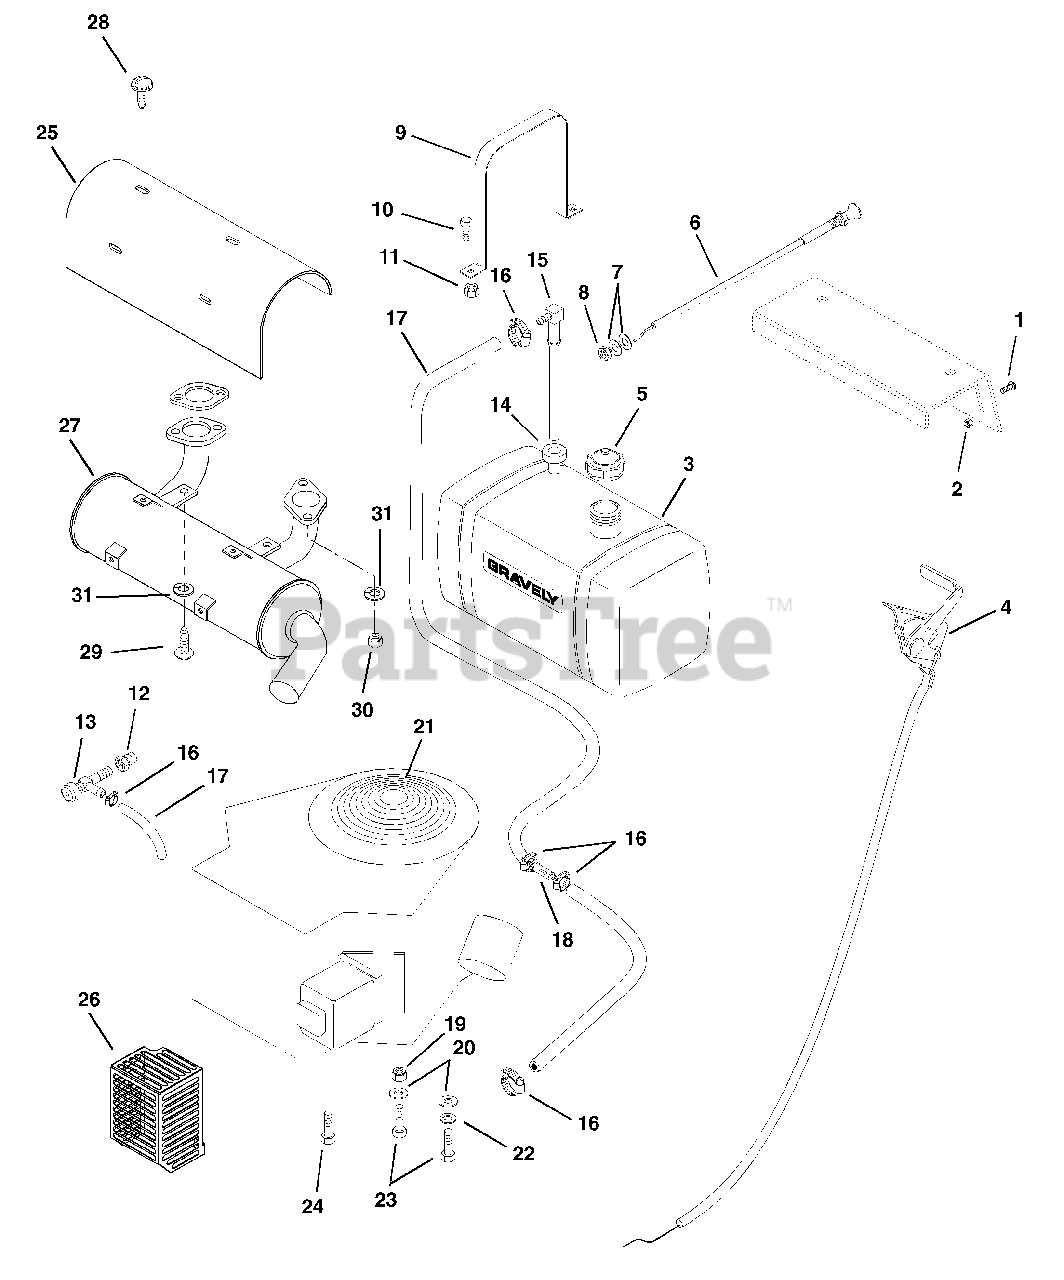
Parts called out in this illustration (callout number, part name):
1	@SCR-MCH 10-24X.50 HWH YWZC
2	@NUT-LK-NYL 10-24 W/INSRT YWZC
3	FUEL TANK
4	CABLE, CONTROL
5	CAP, FUEL TANK
6	CONTROL,CHOKE
7	@WSHR-FL-STL.406X.812X.065 YWZ
8	NUT-JAM .375-24 YWZC
9	RETAINER, 1" ID BEARING
10	@BLT-HEX .25-20X.50 GR5 YWZC
11	@NUT-LK-CTR .25-20 YWZC
12	ADPT,OIL DRAIN
13	DRAIN, 1/2" OIL
14	BSHG-FLG .375 X 1.062 X .625 R
15	FITTING, TANK
16	HOSE CLAMP
17	HOSE, .25 LOW-PERM BULK GAS
18	FILTER,FUEL
19	@NUT-LK-CTR .31-18 YWZC
20	@WSHR-FL-STL.344X.688X.065YWZC
21	ENGINE, 14HP KAWASAKI
22	@WSHR-LK .31X.078 REG YWZC
23	@BLT-HEX M8 X 1.25X30 GR5 YWZC
24	@BLT-HEX .31-18X1.75 GR5 YWZC
25	HEAT SHIELD, CV18-25
26	WLDMT, MUFFLER GUARD
27	MUFFLER
28	SCR-TAP M6-1 X 25MM (BULK)
29	SCR-MCH 8MM-1.25X20 HHCS YWZC
30	NUT-HEX M8-1.25 YWZC
31	@WSHR-LK .31X.078 REG YWZC
